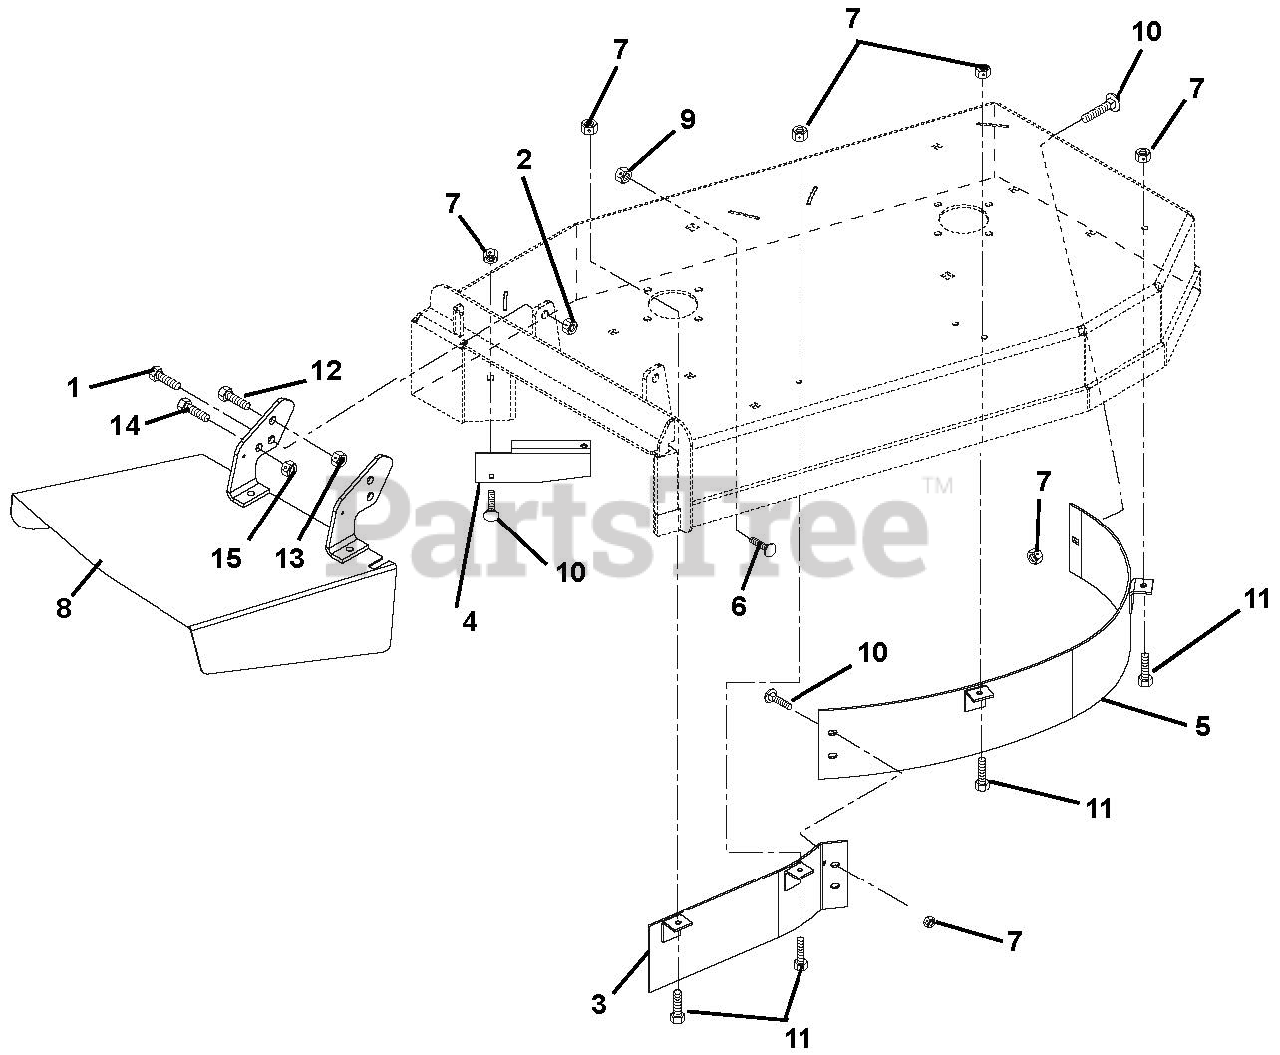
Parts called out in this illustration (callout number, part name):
1	Bolt-Hex .50-13 x 1.25 Grade 5
2	Nut-Locking-Nylon .50-13
3	Weldment- Upper Baffle Right
3	Weldment- Baffle-Right Front- 32"
4	Deflector 32"
5	Weldment- Upper Baffle Left
5	Weldment- Baffle-Left Front- 32"
6	Bolt-Round Head Square Neck .38-16 x 1.00 Grade 5
7	Nut-Locking-Top-Flange .31-18
8	Chute-Discharge
9	Nut-Locking-Top-Flange .38-16
10	Bolt-Round Head Square Neck .31-18 x .75 Grade 5
11	Bolt-Hex .31-18 x .75 Grade 5
12	Bolt-Hex .38-16 x .75 Grade 5
13	Nut-Locking-Center .38-16
14	Bolt-Hex .25-20 x .75 Grade 5
15	Nut-Locking-Nylon .25-20
